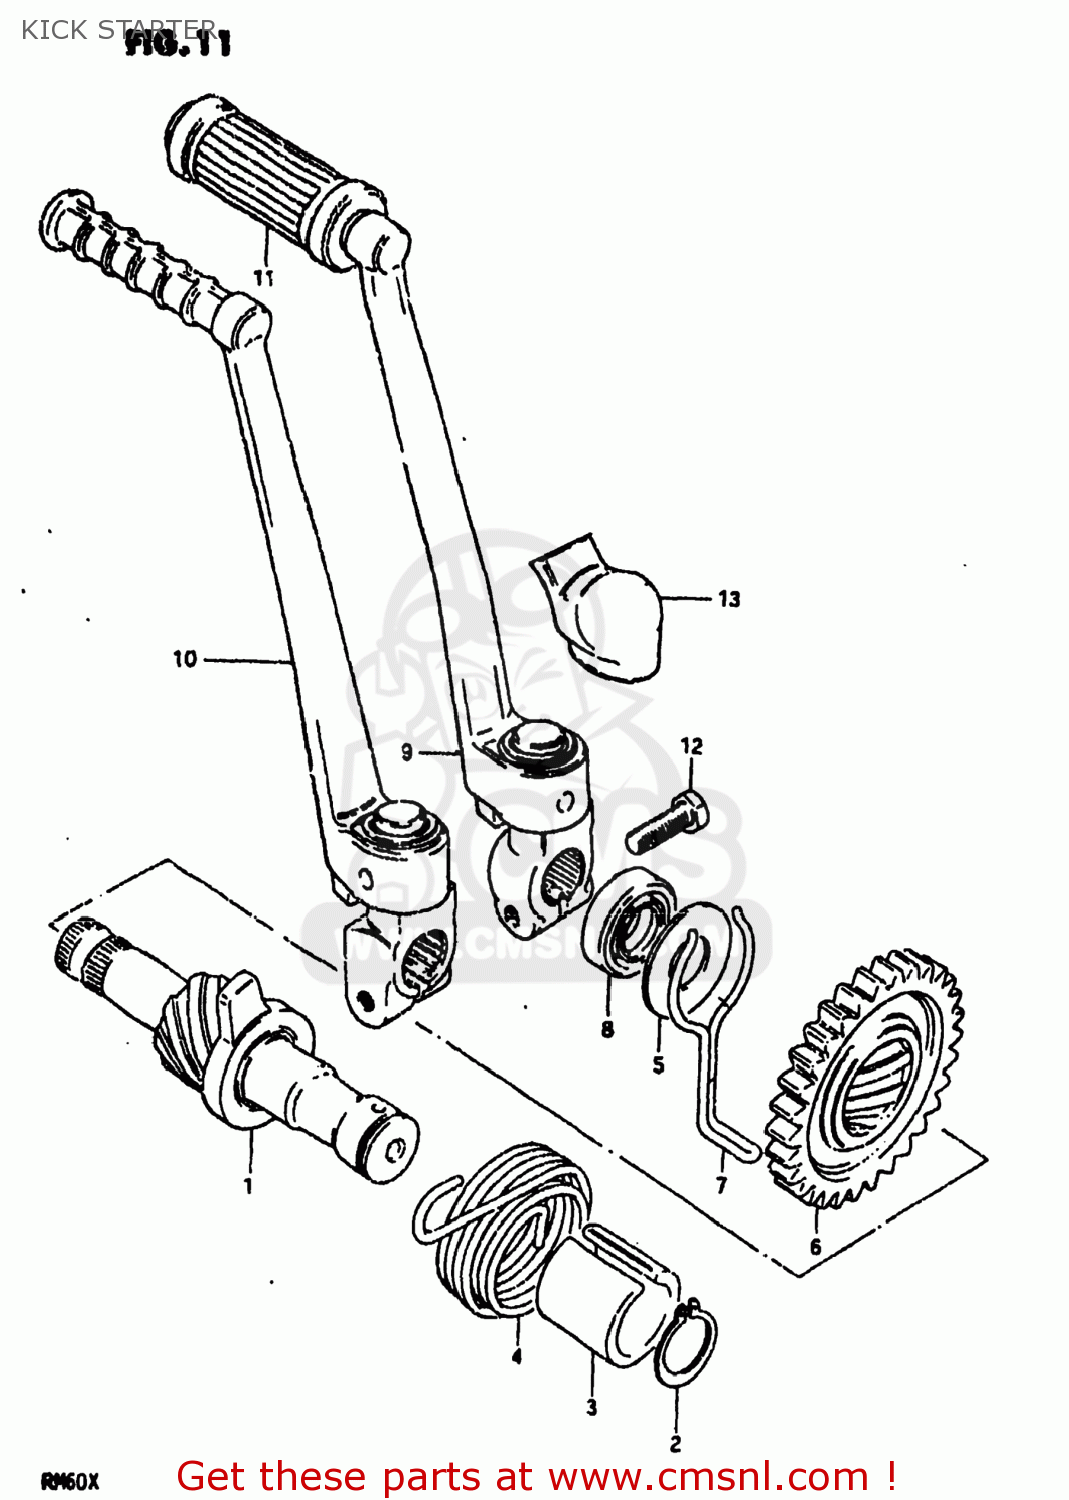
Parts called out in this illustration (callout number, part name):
1	SHAFT,KICK STARTER
2	CIRCLIP,16MM
3	GUIDE,KICK STARTER SFT SPRING
4	SPRING
5	WASHER
6	GEAR,KICK STARTER DRIVE(NT:30)
7	RETAINER,SNAP
8	SEAL,OIL(14X24X6)
9	LEVER ASSEMBLY,KICK STARTER
10	LEVER ASSY,KICK STARTER
11	RUBBER,KICK STARTER PEDAL
12	BOLT
13	COVER,KICK STARTER PEDAL
